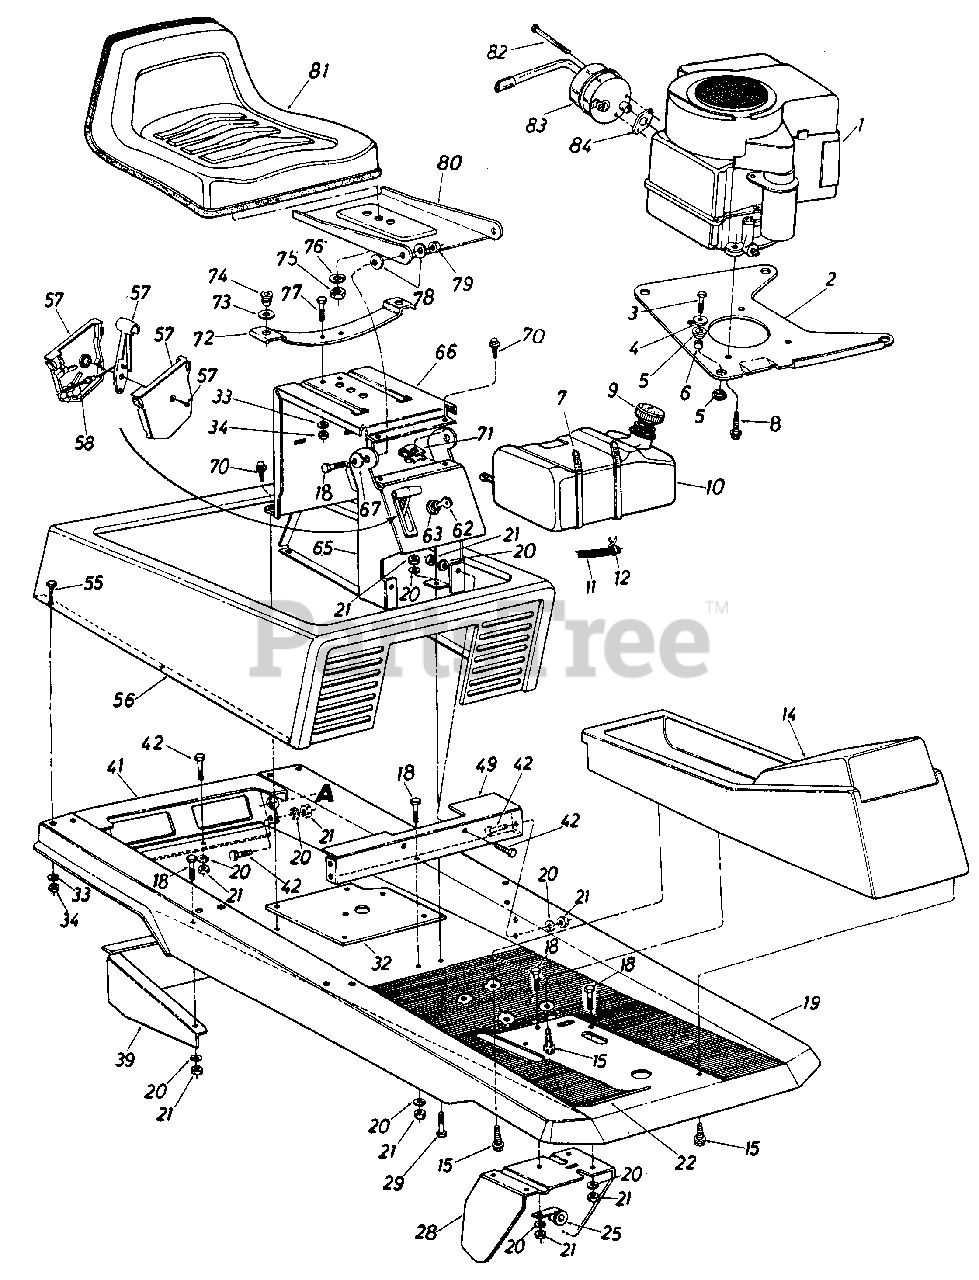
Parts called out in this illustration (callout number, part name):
1	Engine B&S 190707-2159-01
2	PLATE-ENGINE MTG
3	SCREW-HEX 5/16-24 X 1.25
4	WASHER-FL-.312 X 1.125 X .125
5	MOUNT-ENGINE
6	SPACER
7	TIE-CABLE
8	SCREW-HEX SLF TAP 3/8 X 1 3/8
9	GAUGE-GAS
10	TANK-GAS
11	FUEL LINE-15IN
12	CLAMP-HOSE
14	CONSOLE-FR
15	SCREW-PLASTIC-5/16X1.0
18	SCREW-HEX 5/16-18 X .75
20	WASHER-LOCK-5/16
21	NUT-HEX 5/16-18
22	MAT-FLOOR
28	PEDAL ASSY-BRAKE
29	SCREW-HEX 5/16-18 X .62
32	BRACKET-VAR SP MTG
33	LOCK WASHER 1/4 DIA
34	NUT-HEX 1/4-20
49	BRACKET-SEAT SUP
55	SCREW-HEX 1/4-20 X .50
56	COVER ASSY
57	CONTROL-THROTTLE
58	WIRE-CONTROL
62	KEY-IGN (SET OF TWO)
63	SWITCH-IGNITION
65	BRACKET-SEAT
66	KIT-SEAT BRKT ASSY
67	WASHER-BELL .337 X .867 X .057
70	SCREW-HEX WASH SF TAPP
72	SPRING-SEAT
73	WASHER-FL-.531 X .930 OD X .050
75	NUT-HEX 1/2-13
76	WASHER-LOCK-1/2
77	SCREW-HEX 1/4-20 C .62
78	WASHER-BELL .337 X .867 X .057
79	NUT-HEX CENTER L-5/16-18
80	BRACKET-SEAT PIVOT
82	BOLT-SHD 3/8
84	GASKET-EXHAUST
